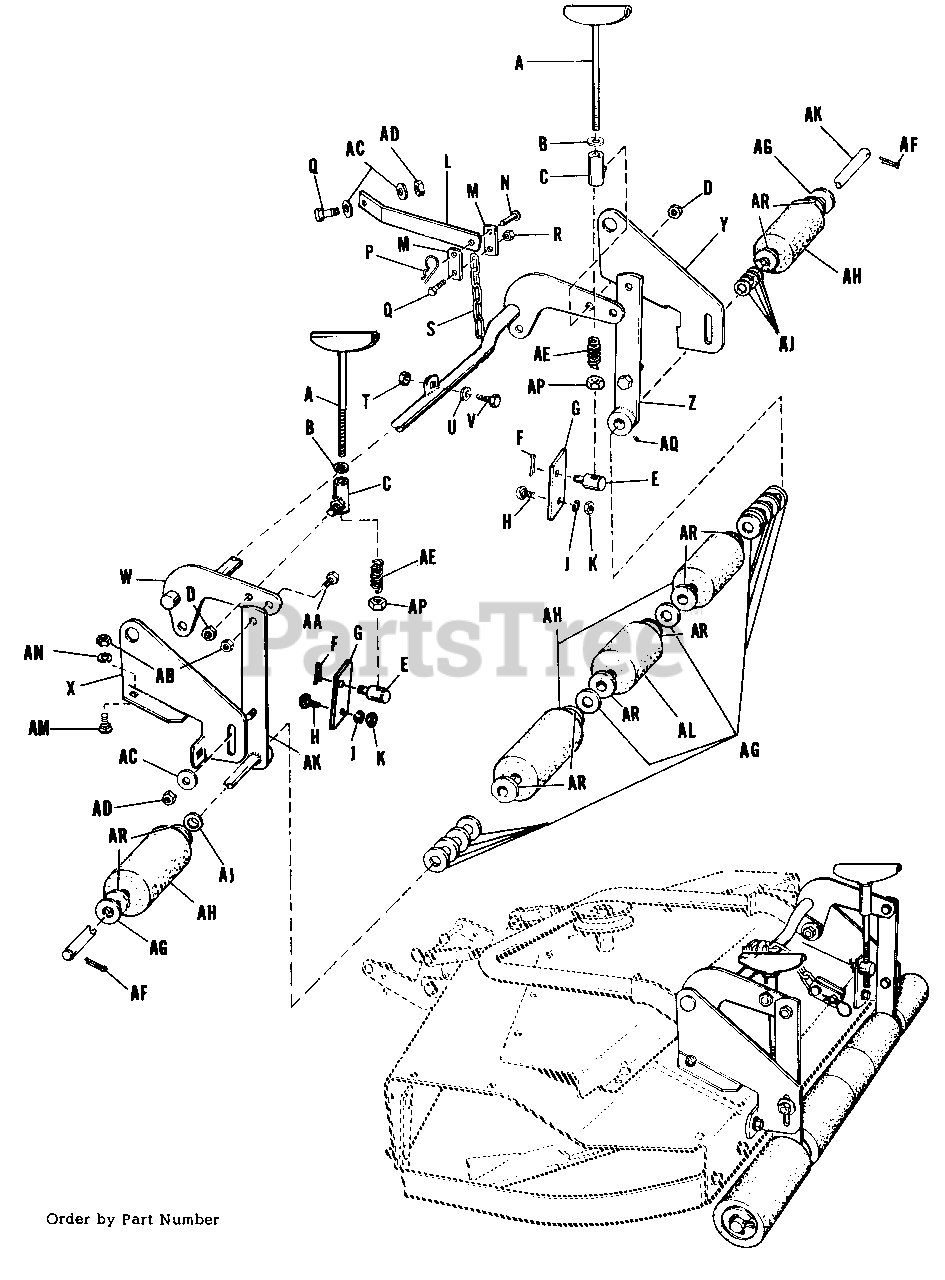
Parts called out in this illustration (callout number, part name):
A	Screw Assembly, Adjusting
B	Washer, Plain, 3/8"
C	Socket Assembly, Crank
D	Nut, Hex, Full, Lock, 3/8"-16 NC
F	Cotter Pin, 3/32" x 3/4" lg.
G	Link, Lift
H	Bolt, Carriage, 3/8"-16 NC x 3/4" lg.
J	Washer, Lock, 3/8"
K	Nut, Hex, Full, 3/8"-16 NC
L	Lever, Mower Lift
M	Link, Mower Lift
P	Clip, Spring
Q	Capscrew, Hex Hd., 3/8"-16 NC x 1" lg.
R	Nut, Hex, Full, Lock, 3/8"-16 NC
T	Nut, Hex, Full, Lock, 3/8"-16 NC
U	3/8" Washer
V	Capscrew, Hex Hd., 3/8-16 x 1" lg.
W	Arm Assembly, Rocker
X	Bracket, Roller, L.H.
Y	Bracket, Roller, R.H.
Z	Bar Assembly, Roller
AA	Capscrew, Hex Hd., 3/8"-16 NC x 1" lg.
AB	Nut, Hex, Full, 3/8"-16 NC
AC	Washer, Plain, 3/8"
AD	Nut, Hex, Full, Lock, 3/8"-16 NC
AE	Spring, Adj. Screw
AF	Pin, Cotter, 3/16" x 1" lg.
AH	Roller w/Bushing
AK	Shaft & Support Arm.
AL	ROLLER, .652 ID, 2.50 OD, 4.10 LG
AM	Bolt, Carriage, 3/8"-16 NC x 3/4" lg.
AN	Washer, Lock, 3/8"
AP	Nut, Hex. Full
AQ	Set Screw
